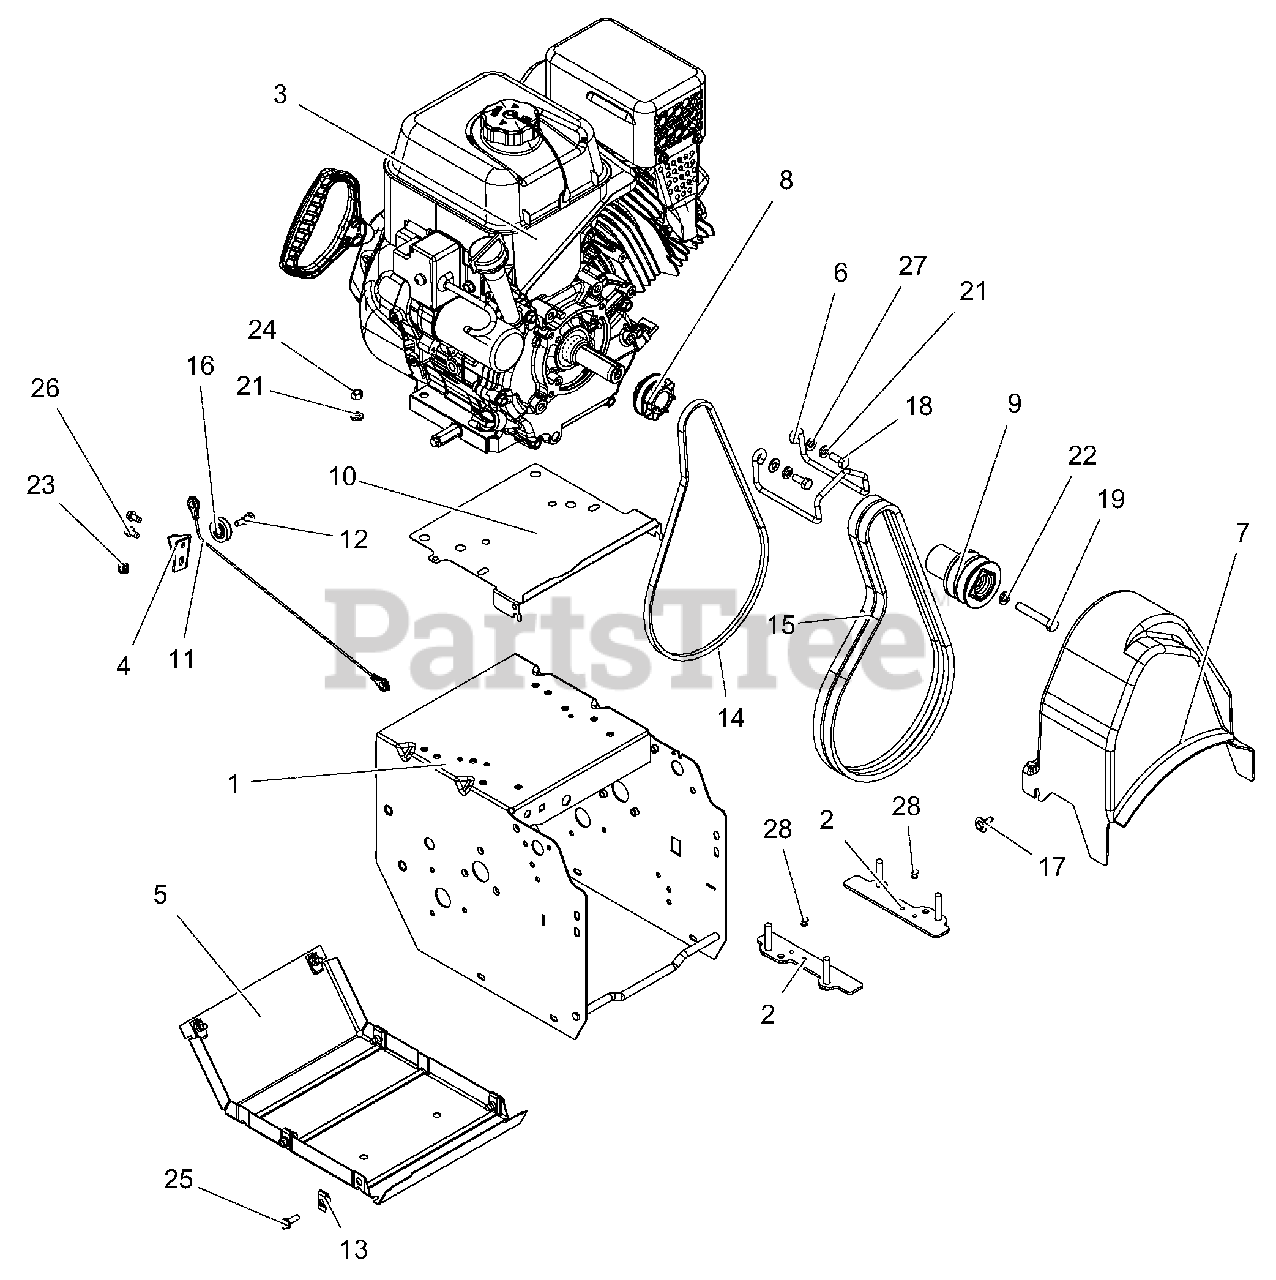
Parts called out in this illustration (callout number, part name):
1	WELDMENT, FRAME - DELUXE 16"
2	STRAP,ENGINE BOLT,ARIENS LRG
3	ENGINE, ARIENS AX414 120V/60W
4	BRACKET, CABLE PULLEY
5	COVER, BOTTOM
6	FINGER, BELT
7	BELT COVER
8	SHEAVE, DRIVE
9	SHEAVE,ATTACHMENT 2-GRV
10	BAFFLE,ENGINE,ARIENS LRG BLOCK
11	CABLE, LOWER TRACTION (DELUXE)
12	BOLT, SHLDR-.375X.375X.25-20
13	NUT-RTNR .25-20X.56
14	V-BELT, 3L-WRAPPED
15	V-BELT, HA-RAW EDGE (SET)
16	PULLEY, CABLE
17	SCR-TAP .25-20X.5 CAPTIVE
18	BLT-HEX .31-24X.75 YWZC GR5
19	BLT-HEX .38-24X2.25 YWZC GR5
21	WSHR-LK .312X.097 HVY YWZC
22	@WSHR-LK .38X.094 REG YWZC
23	@NUT-LK-CTR-FLG .25-20 YWZC
24	@NUT-HEX .31-18 YWZC
25	BLT-HEX .25-20X.75 HWH YZ GR5
26	SCR-TAP .25-20X.50 HWH TR YWZ
27	@WSHR-FL-STL.344X.688X.065YWZC
28	RVT-POP .187 YZ
